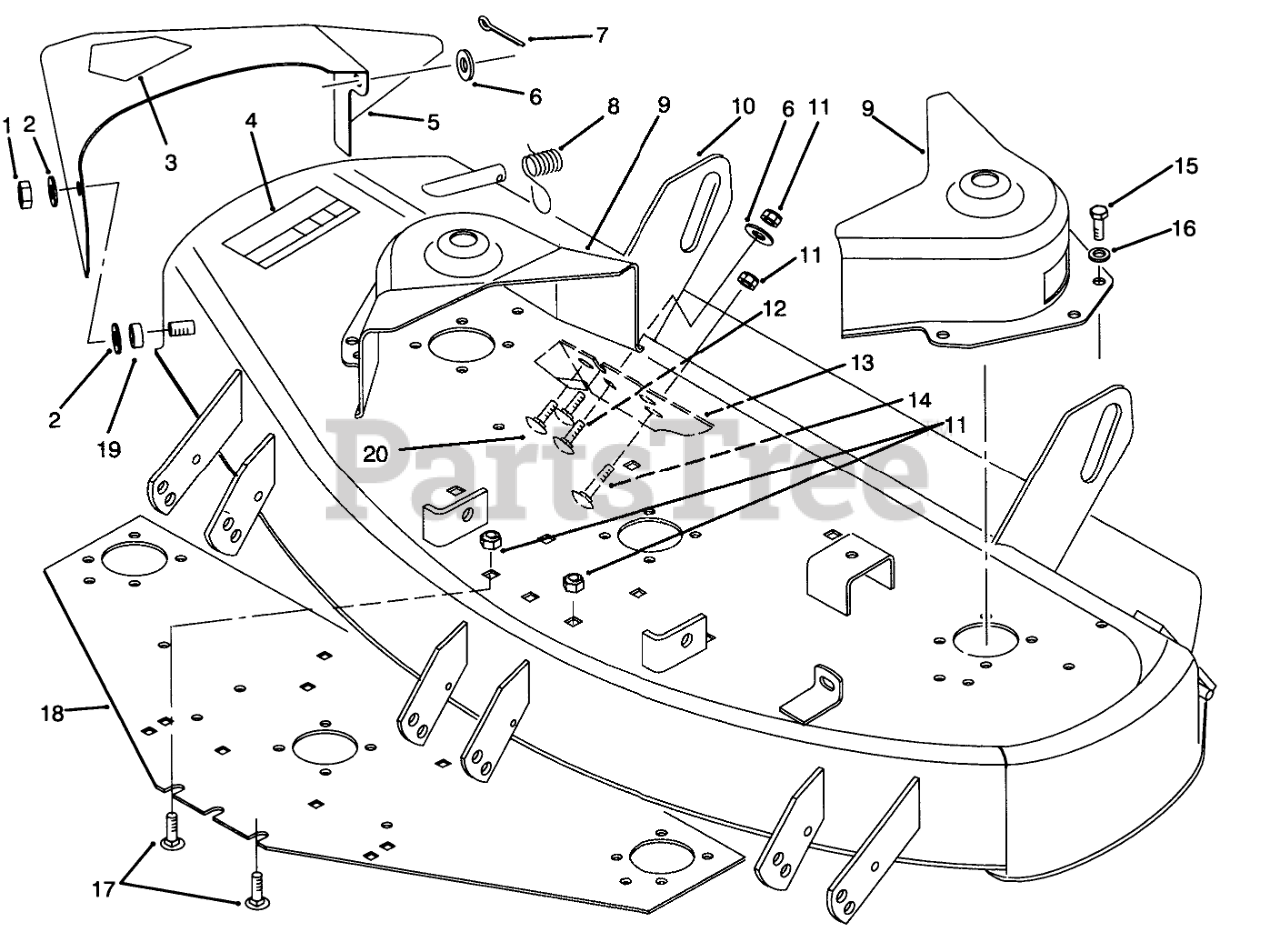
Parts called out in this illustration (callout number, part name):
1	NUT-HJ
2	Washer
3	DECAL-DANGER
4	DECAL-DANGER
5	Chute/Decal Assembly (Incl. Ref. #3)
6	WASHER-FLAT
7	PIN-COTTER
8	Spring
9	COVER-BELT
10	Deck/Safety Decal Assy. (Incl. Ref. #4, pg.1 Ref. #21, pg. 3)
11	NUT-LOCK, NI
12	SCREW-CARR
13	Plate-Wear
14	SCREW-CARR
15	Bolt
16	WASHER-FLAT
17	SCREW-CARR
18	Plate-Deck
19	BUSHING-PIVOT
20	BOLT-CARR
